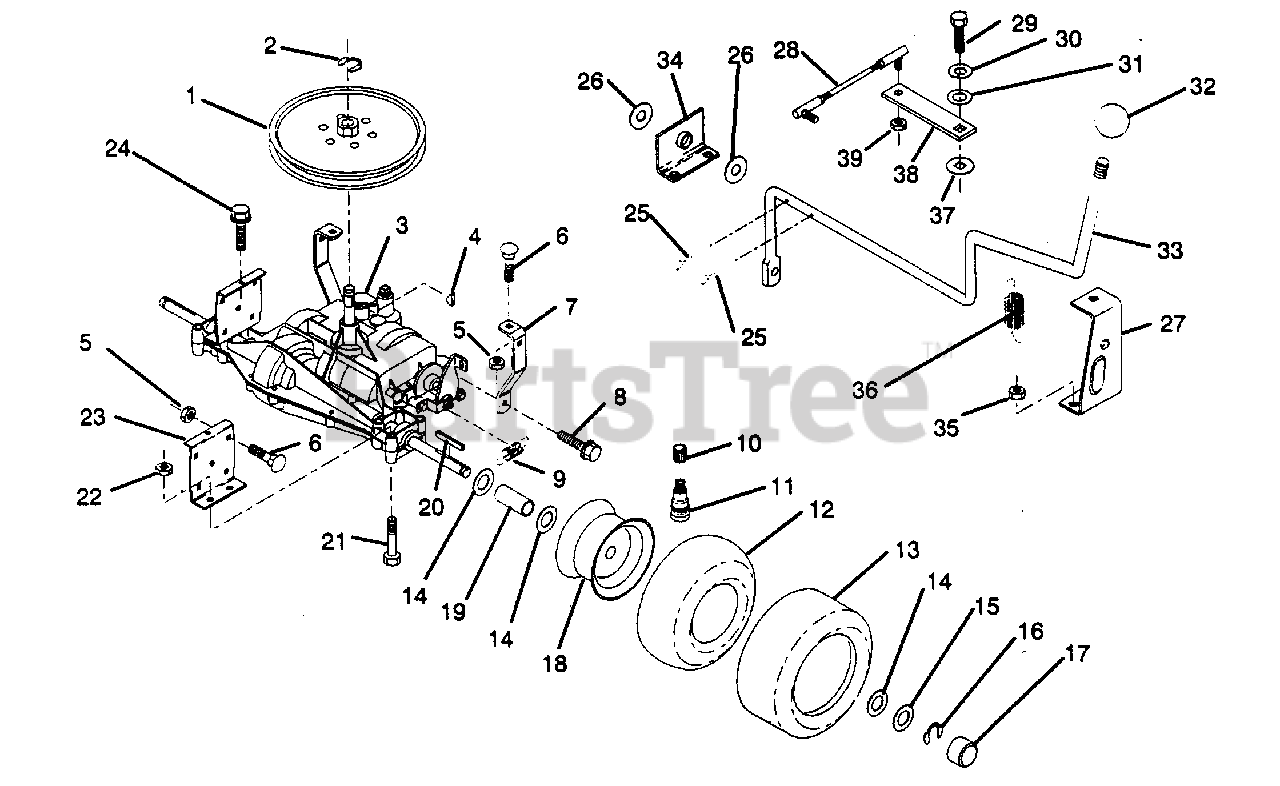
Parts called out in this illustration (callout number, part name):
1	Pulley (AYP part number)
2	Ring, Retainer (AYP part number)
3	Transaxle, Foot, 4 Speed (AYP part number)
4	Key, Woodruff #9 (AYP part number)
5	Nut, Crownlock 5/16-18
6	Bolt, Carriage 5/16-18 UNC x 3/4
7	Strap, Torque (AYP part number)
8	Screw, Hex Thdrol. 5/16-18 x 1/2 (AYP part number)
9	Spring, Brake (AYP part number)
10	Cap, Valve (AYP part number)
11	Stem, Valve (AYP part number)
12	Tube (AYP part number)
13	Tire, Rear (AYP part number)
14	Washer 25/32 x 1-1/4 x 16 Ga. (AYP part number)
15	Washer, 25/32 x 1-5/8 x 16 Ga. (AYP part number)
16	E-Ring (AYP part number)
17	Hub, Cap (AYP part number)
18	Rim (AYP part number)
19	Spacer (AYP part number)
20	Key, Square (AYP part number)
21	Bolt, Fin, Hex 3/8-16 x 2-3/4 (AYP part number)
22	Nut, Crownlock 3/8-16
23	Bracket, Transaxle (AYP part number)
24	Screw, 5/16-18 x 3/4
25	Pin, Cotter 1/8 532 1 (AYP part number)
26	Washer 17/32 x 1 x 16 Ga. (AYP part number)
27	Support, Handle Shift R.H. (AYP part number)
28	Link, Shift (AYP part number)
29	Bolt, Fin, Hex 1/4-28 UNF x 3/4 Gr.8 (AYP part number)
30	Washer, Lock Hvy. Helical Spring 1/4 (AYP part number)
31	Washer 9/32 x 3/4 x 10 Ga. (AYP part number)
32	Knob, Shift Contol (AYP part number)
33	Shift Rod (AYP part number)
34	Support, Handle Shift L.H. (AYP part number)
35	Nut, Keps 5/16-18 (AYP part number)
36	Extension, Spring (AYP part number)
37	Washer, Shift Plate (AYP part number)
38	Arm, Shift (AYP part number)
39	Nut, Hex Nylon 5/16-24 (AYP part number)
